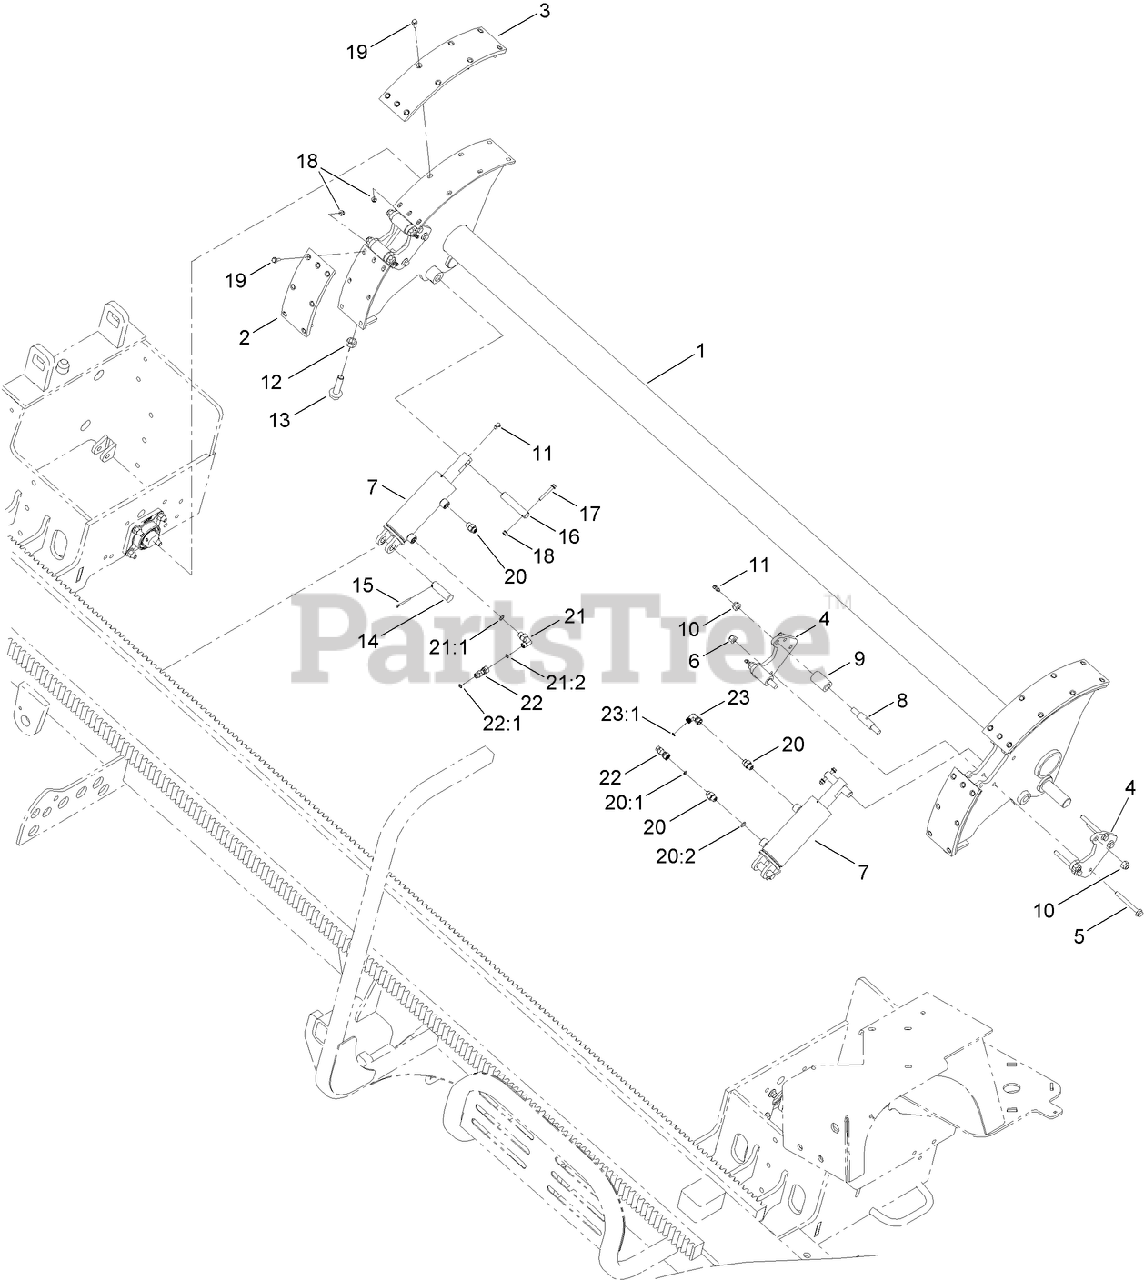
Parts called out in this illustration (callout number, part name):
1	CAM-LOADER, ROD
2	PAD-WEAR, ROD LOADER (SHORT)
3	PAD-WEAR, ROD LOADER (LONG)
4	PLATE-HOLDER, PIPE
5	SCREW-HHF
6	NUT-LOCK, NI
7	HYD CYLINDER ASM
8	SHAFT-ROLLER, PIPE
9	TUBE-ROLLER
10	NUT-HEX
11	FITTING-GREASE, 90 DEG
12	NUT-HEX
13	SCREW-HHF
14	PIN-CLEVIS
15	PIN-COTTER
16	PIN-STRAIGHT
17	SCREW-HHF
18	NUT-FLANGE, NI
19	SCREW-HHF
20	FITTING-STRAIGHT
20:1	O-RING
20:2	O-RING
21	FITTING-ELBOW 90
21:1	O-RING
21:2	O-RING
22	FITTING-STRAIGHT
22:1	O-RING
23	FITTING-ADAPTOR
23:1	O-RING
